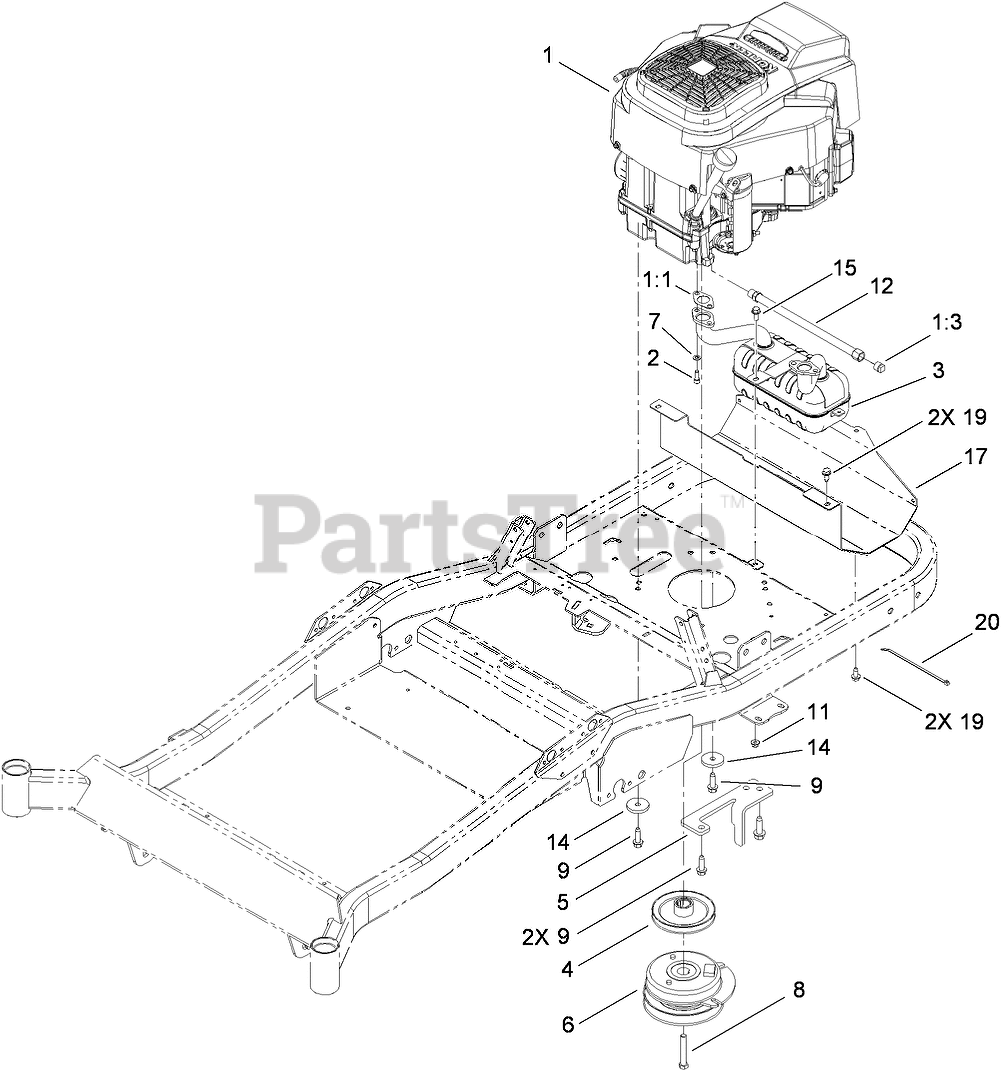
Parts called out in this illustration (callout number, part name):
1:1	GASKET-EXHAUST
1:3	PLUG-PIPE, SQH
2	SCREW-HSH
3	MUFFLER-TWIN, KOHLER
4	PULLEY-ENGINE
5	BRACKET-STOP, PTO
6	CLUTCH-PTO
7	WASHER-LOCK
8	SCREW-HH
9	SCREW-TAPTITE
11	NUT-HF, NI
12	HOSE-DRAIN, OIL
14	WASHER-PLAIN
15	SCREW-HHF
17	SHIELD-HEAT
19	SCREW-HWHTF
20	TIE-CABLE
